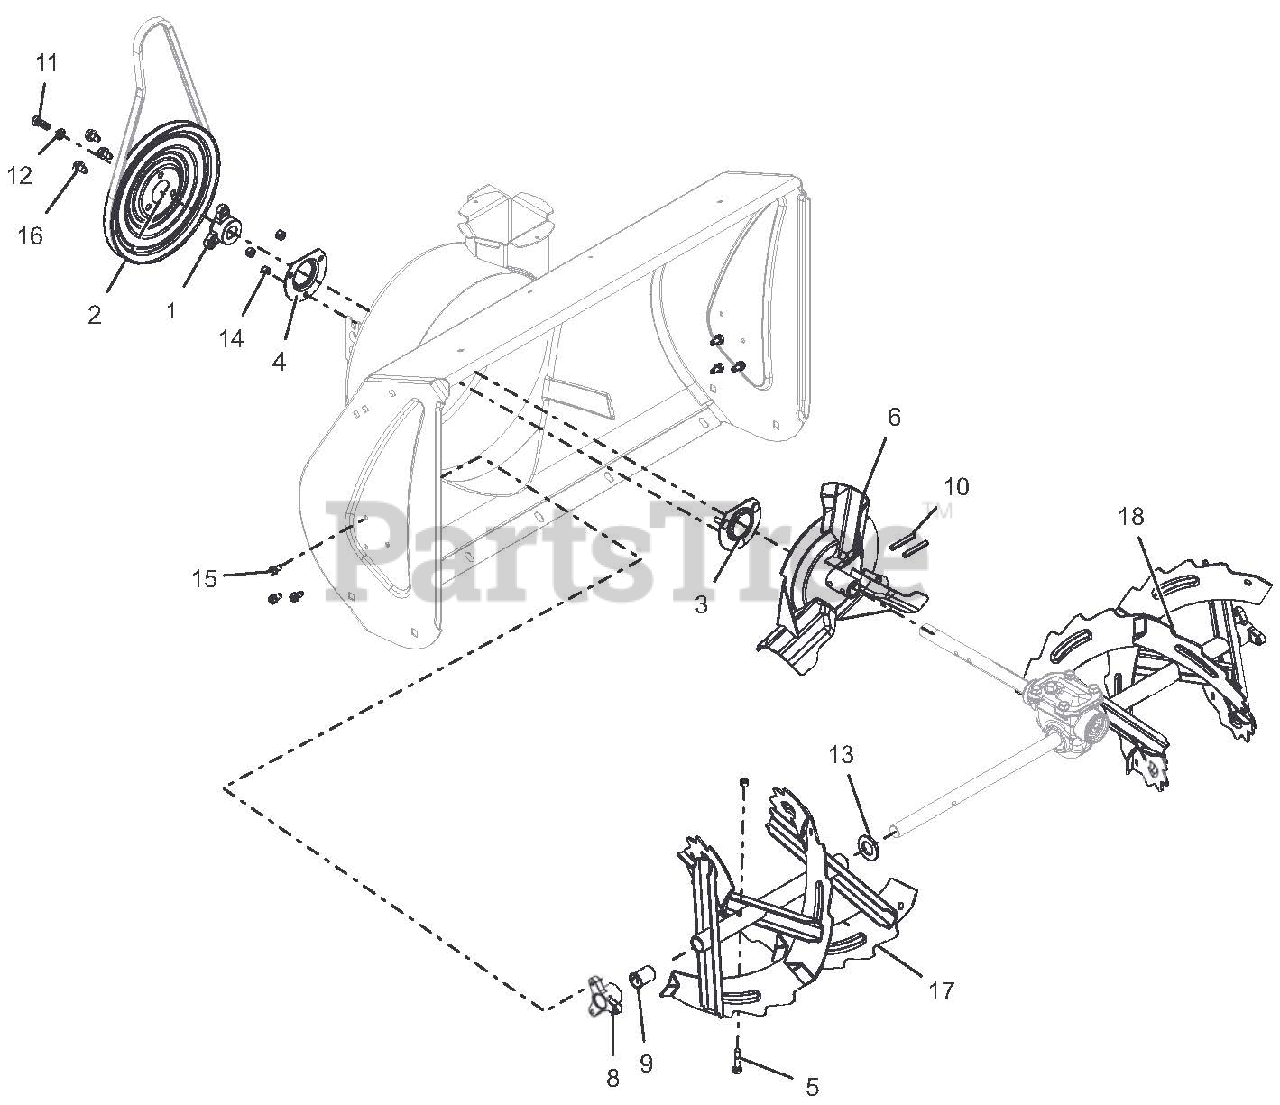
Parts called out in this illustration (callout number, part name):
1	PULLEY HUB, BOLT-ON D-BORE .75
2	PULLEY,SPIN FORM SINGLE GROOVE
3	BEARING FLANGE
4	BEARING FLANGE
5	SHEAR BOLT
6	IMPELLER, COMPACT 12" 3-BLADE
8	BUSHING, RAKE SHAFT .75"
9	BSHG-FLG SPLIT NYLINER .75"ID
10	PIN-ROLL .250X1.75
11	BLT-HEX .31-24X.75 YWZC GR5
12	WSHR-LK .312X.097 HVY YWZC
13	@WSHR-FL-STL.812X1.50X.135YWZC
14	@NUT-LK-CTR .25-20 YWZC
15	SCR-TAP .25-20X.50 HWH TR YWZ
16	@SCR-TAP .31-18X.50 HWH TR YWZ
17	RAKE, 28" RH, BLK SERR W/ZERK
18	RAKE, 28" LH, BLK SERR W/ZERK
